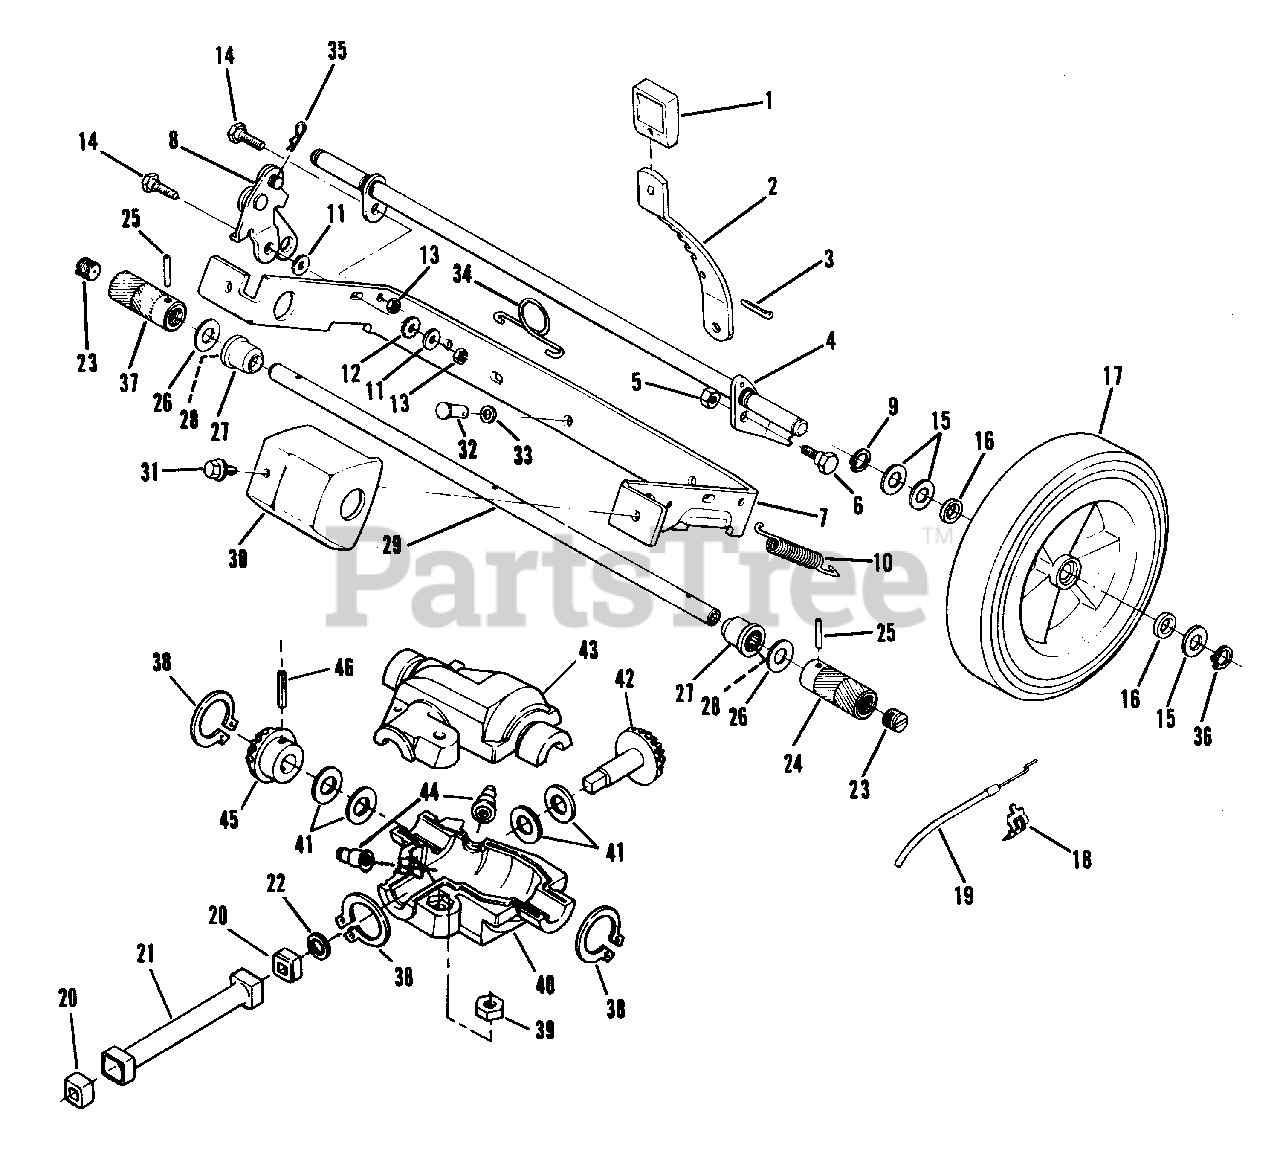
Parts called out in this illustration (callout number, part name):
1	Knob-Rear Ht. Adj. Lever
2	Lever-Rear Height Adjust
3	Cotter Pin
4	Axle Assembly
5	Locknut
6	Bolt-Shoulder
7	Bracket-21" Axle
8	Clutch Assembly
9	Retaining Ring
10	Spring
11	Washer
12	Lockwasher
13	Stop Nut
14	Bolt-Shoulder
15	Washer
16	Washer-Felt
17	Wheel-Rear
18	Clip
19	Cable-Starter Interlock
20	Bushing
21	Tube-Drive
22	"O" Ring-Spacer
23	Plug
24	Drive Roller-L.H.
25	Pin-Spiral
26	Washer
27	Sleeve & Bearing Assembly
28	Needle Bearing
29	Shaft
30	Guard-Roller
31	Screw-Sems
32	Pin-Rear Height Adjust Lever
33	Spring Washer
34	Spring-Height Adjust
35	Lock Pin
36	Retaining Ring
37	Drive Roller-R.H.
38	Ring-Retaining
39	Locknut
40	Gear Box-Lower
41	Washer
42	Gear-Drive
43	Gear Box-Upper
44	Zerk Fitting
45	Gear-Driven
46	Roll Pin
